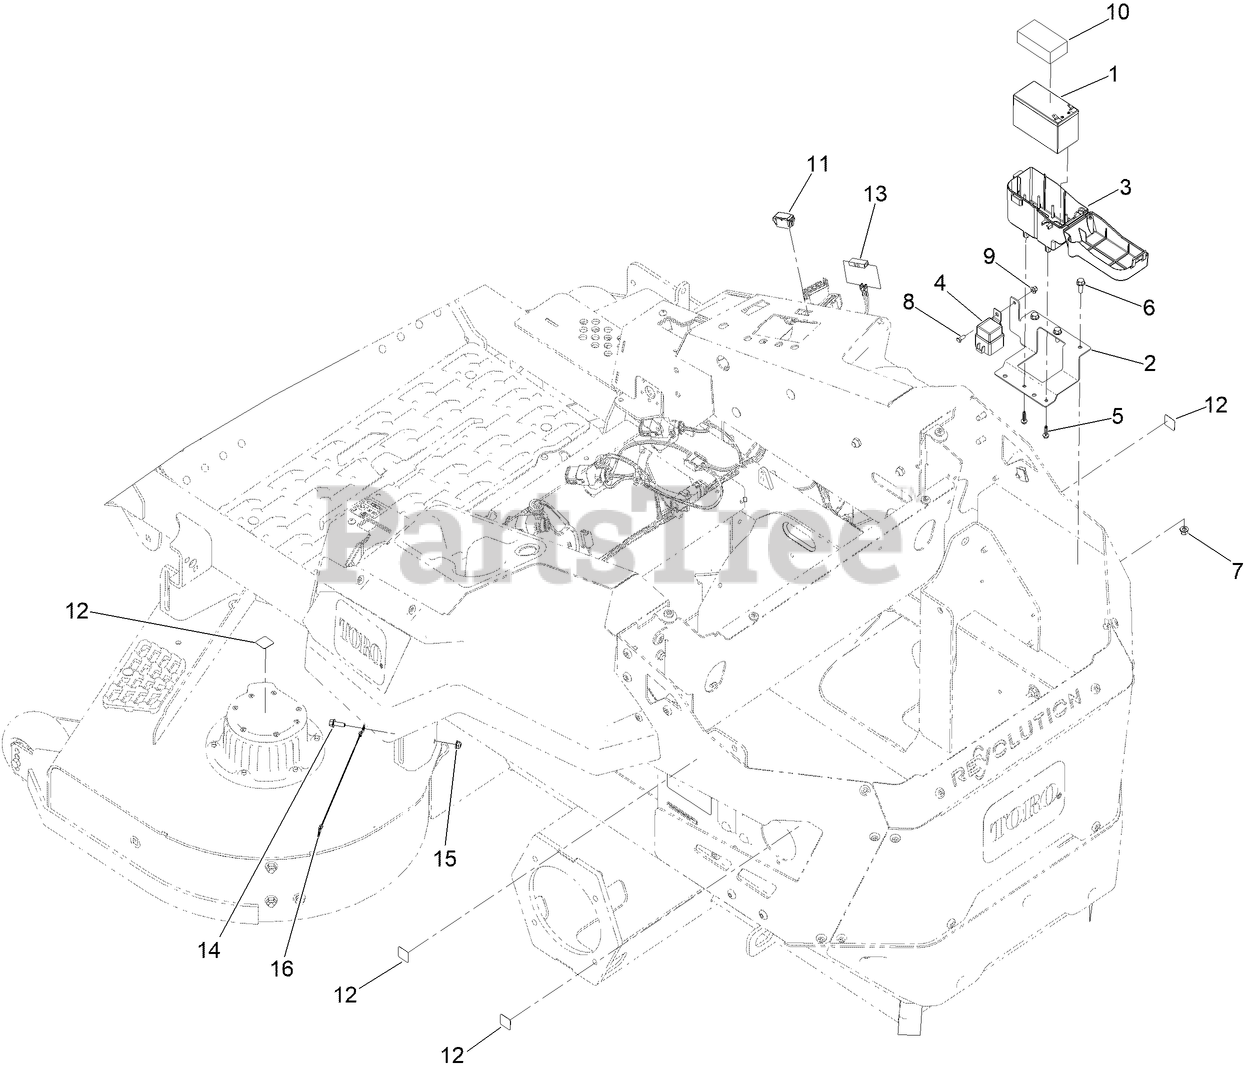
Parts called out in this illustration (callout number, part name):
1	BATTERY-NONSPILLABLE, 12 V
2	BRACKET-BATTERY
3	BATTERY BOX ASM
4	RELAY-MINI
5	SCREW-PLASTIC, HWH
6	SCREW-HHF
7	NUT-FLANGE, NI
8	SCREW-HH
9	NUT-FLANGE, NI
10	FOAM-BATTERY, TOP
11	PLUG-HOLE
12	DECAL-VOLTAGE, HIGH
13	ADAPTER-TERMINAL, TAB-TO-TAB
14	SCREW-HHF
15	NUT-HF
16	CABLE-STRAP, BRAIDED
